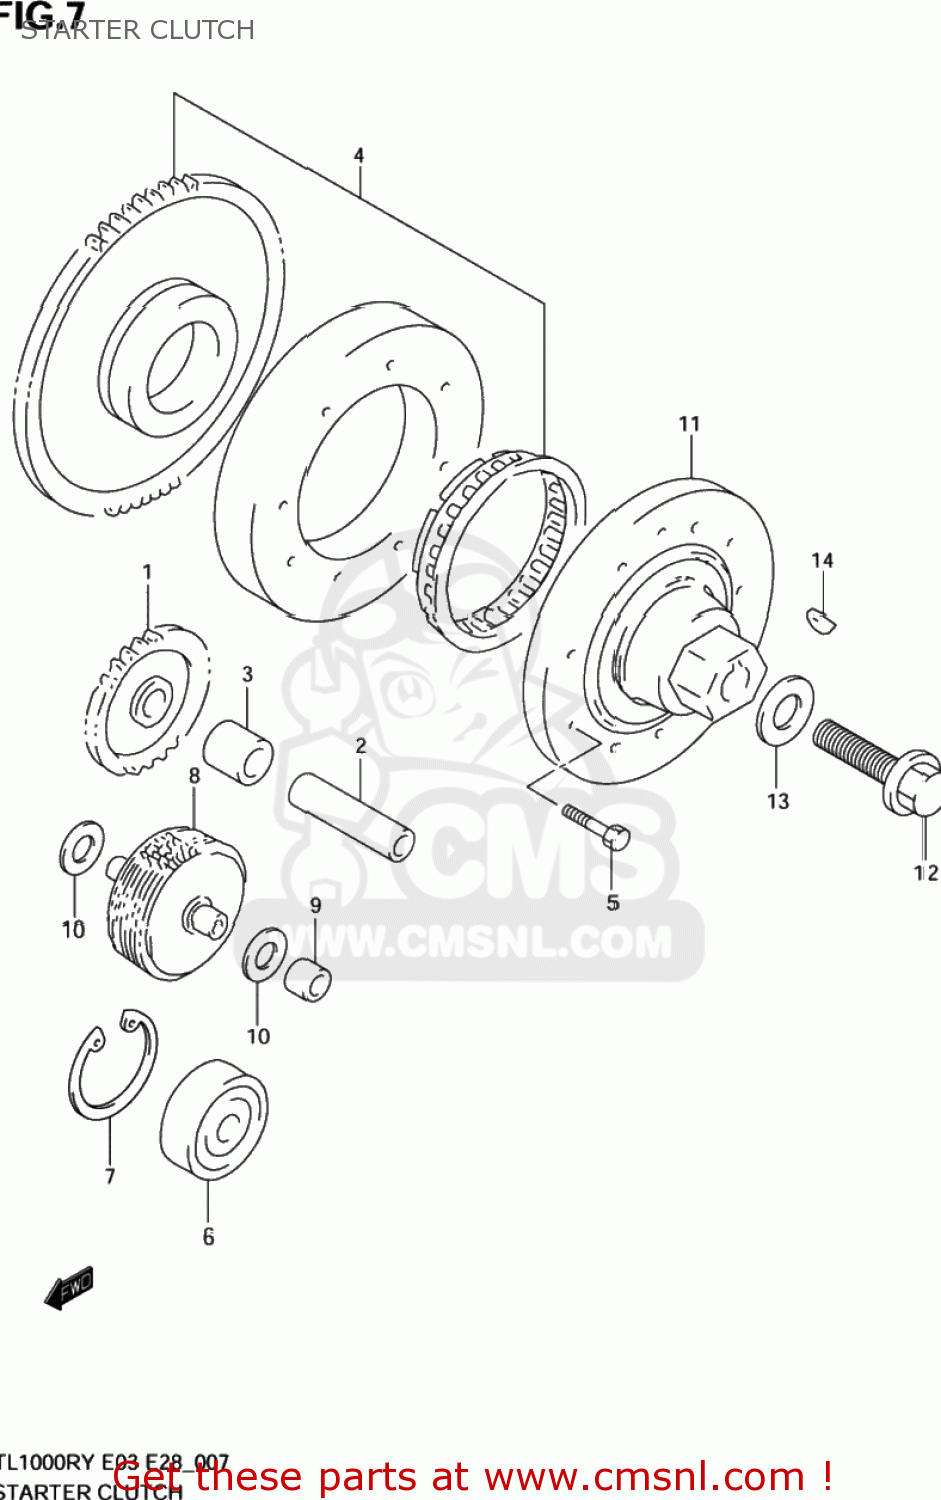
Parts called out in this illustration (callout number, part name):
1	GEAR,STARTER IDLE NO.2
2	PIN(7X12X50.5)
3	SPACER(12.5X19X17.5)
4	CLUTCH SET,STARTER
5	BOLT
6	BEARING(12X28X8)
7	CIRCLIP
8	LIMITER ASSEMBLY,STARTER IDLER GEAR
9	BUSH,LIMITER GEAR SHAFT
10	WASHER
11	HOUSING,STARTER CLUTCH
12	BOLT(12X40)
13	WASHER(12X30X3)
14	KEY
